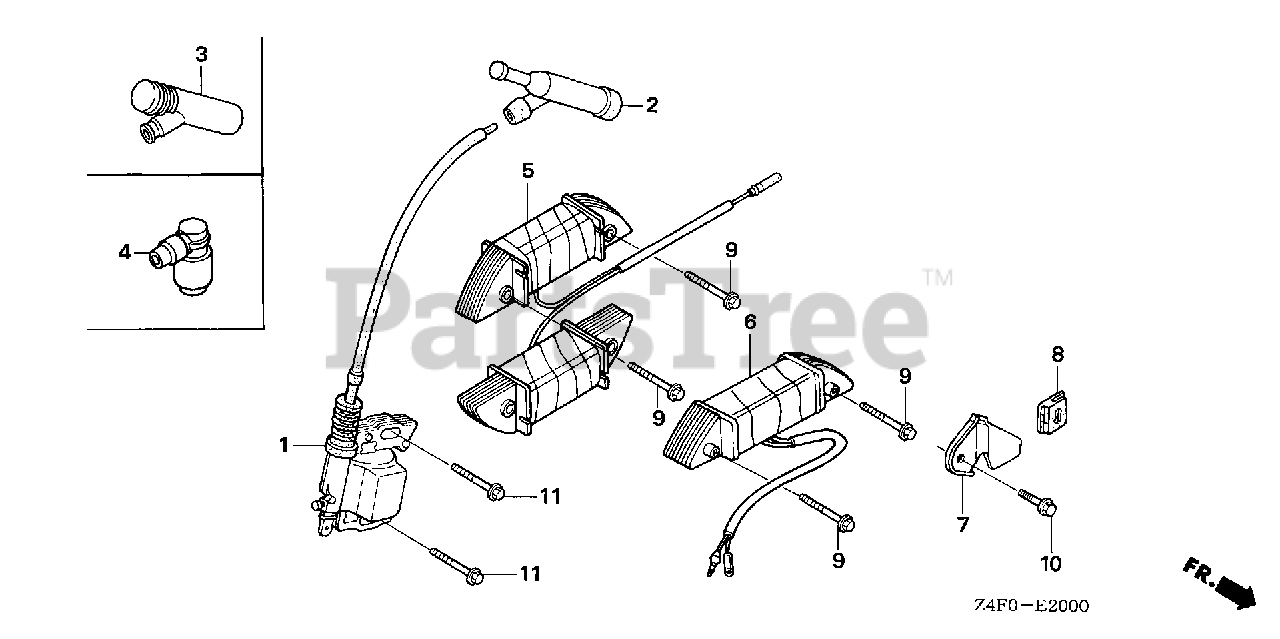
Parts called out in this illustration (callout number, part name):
1	COIL ASSY., IGNITION
2	CAP ASSY., NOISE SUPPRESSOR (NICHIWA Y-EZ RTFM256)
5	COIL ASSY., LAMP (12V/50W)
7	CLAMP, WIRE
8	GROMMET, WIRE
9	BOLT, FLANGE (6X28) (CT200)
10	BOLT, FLANGE (5X10)
11	BOLT, FLANGE (6X25) (CT200)
